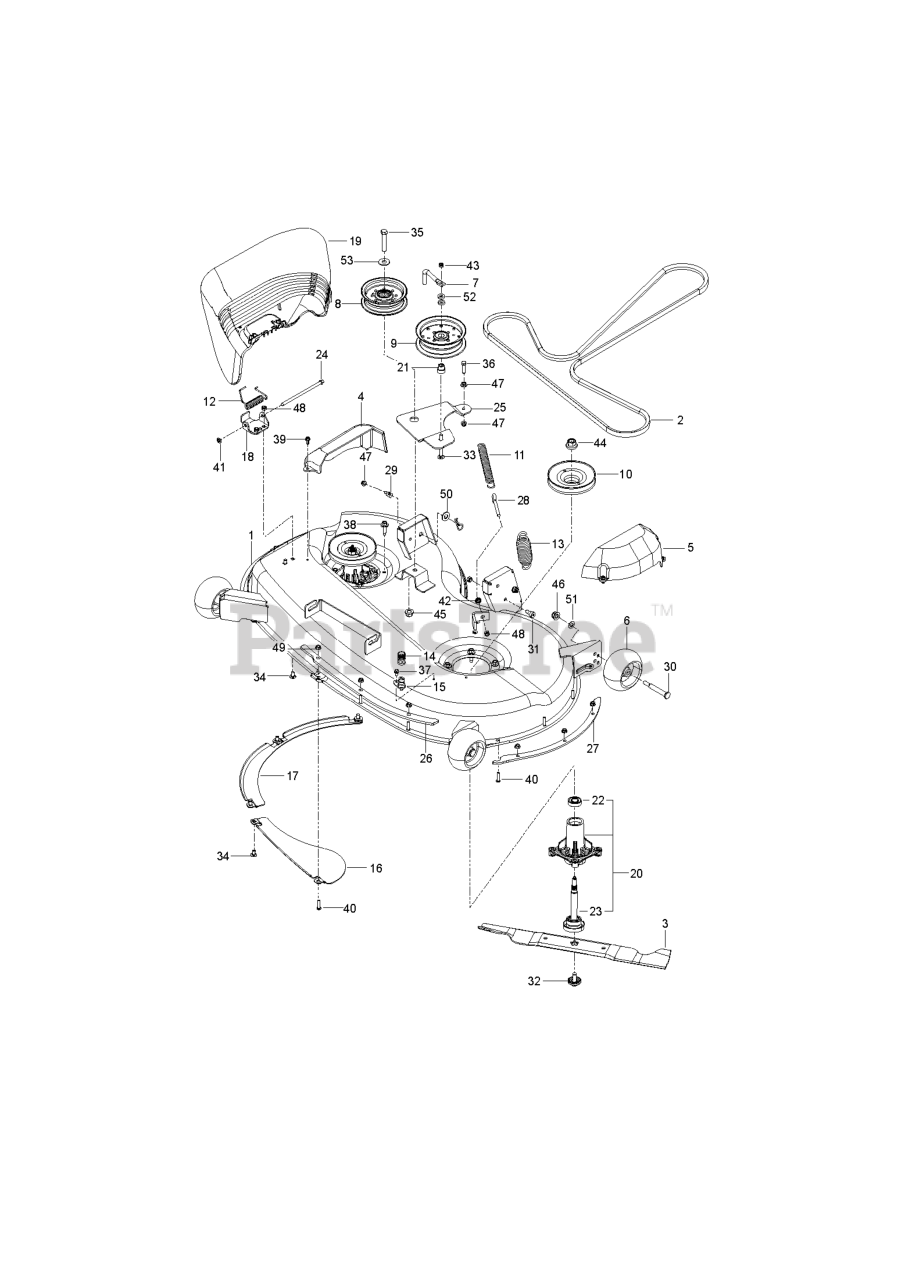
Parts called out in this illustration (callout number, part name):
1	Decks
3	BLADE.MOWER.46".HI.LIFT
4	COVER.MANDREL.RH.46"
6	WHEEL.GAUGE.RALLY
7	BELT KEEPER 5"
8	PULLEY.IDLER.MWR.STATI.LH
9	PULLEY.IDLER.DECK
10	PULLEY.MANDREL.46"
11	SPRING.EXTENSION
12	SPRING, TORSION
13	SPRING
14	COUPLING.QUICK CONNECT
15	PORT.WASHOUT
16	BAFFLE CENTER FRONT
17	BAFFLE FRONT RH
18	BRKT.DEFLECTOR.38"2005+
19	SHIELD.DEFLECTOR.MOWER.46"BLAC
20	MANDREL.W/SPCR.BRG.SHRT.NONRVL
21	IDLER BUSHING
22	BEARING.MANDREL.TOP.EXTENDED
23	SHAFT
24	ROD.HINGE
25	ARM.PNT.CLTCHG.STMP.46.RZ.EDIP
26	PLATE.PNT.REINF.DECK.46".EDIP
27	PLATE.REINFOR.46.SIDEBOLT.X431
28	EYE BOLT 5/16 X 3.50
29	STUD.FASTNER.W/ANTI-ROTATE
30	BOLT.SHOULDER.3/8-16X3-5/8.
31	SB 3/8-16 X 3/8 SKT HD ZD
32	SCREW.SEMS.7/16-20X1.HEX.HEAD
33	BOLT CARRIAGE
34	RP BOLT 5/16-18 X3/4 ZN/YEL GR
34	BOLT 5/16C X 3/4" CARRIAGE
35	BOLT.HEX.7/16-14
36	BOLT.5/16-18X1-1/4 FULL THD
37	SCREW #10 X 1/2 SELF TAPPING
38	BOLT.HEX.WASHR.HED.313-18X1.19
39	SCREW.1/4-20X5/8
40	SCREW.BUTTONHEAD.1/4-20X1
41	NUT PUSH M
42	NUT 5/16C WHIZ
43	NUT HEX 3/8-16 NYLON, THIN
44	NUT.FLANGE.LOCK.TOP
45	NUT.LOCK.FLANGE.7/16
46	NUT LOCK FLG 3/8-16 UNC
47	5/16-18 NYLOC FLANGE NUT
48	NUT.71038.31-18.HEX.NYLOCK
49	NUT T
50	WASHER
51	WASHER 5/16 FLAT
52	WASHER 3/8 X 3/4 X .187 TK
53	WASHER 7/16 FLAT ZD
